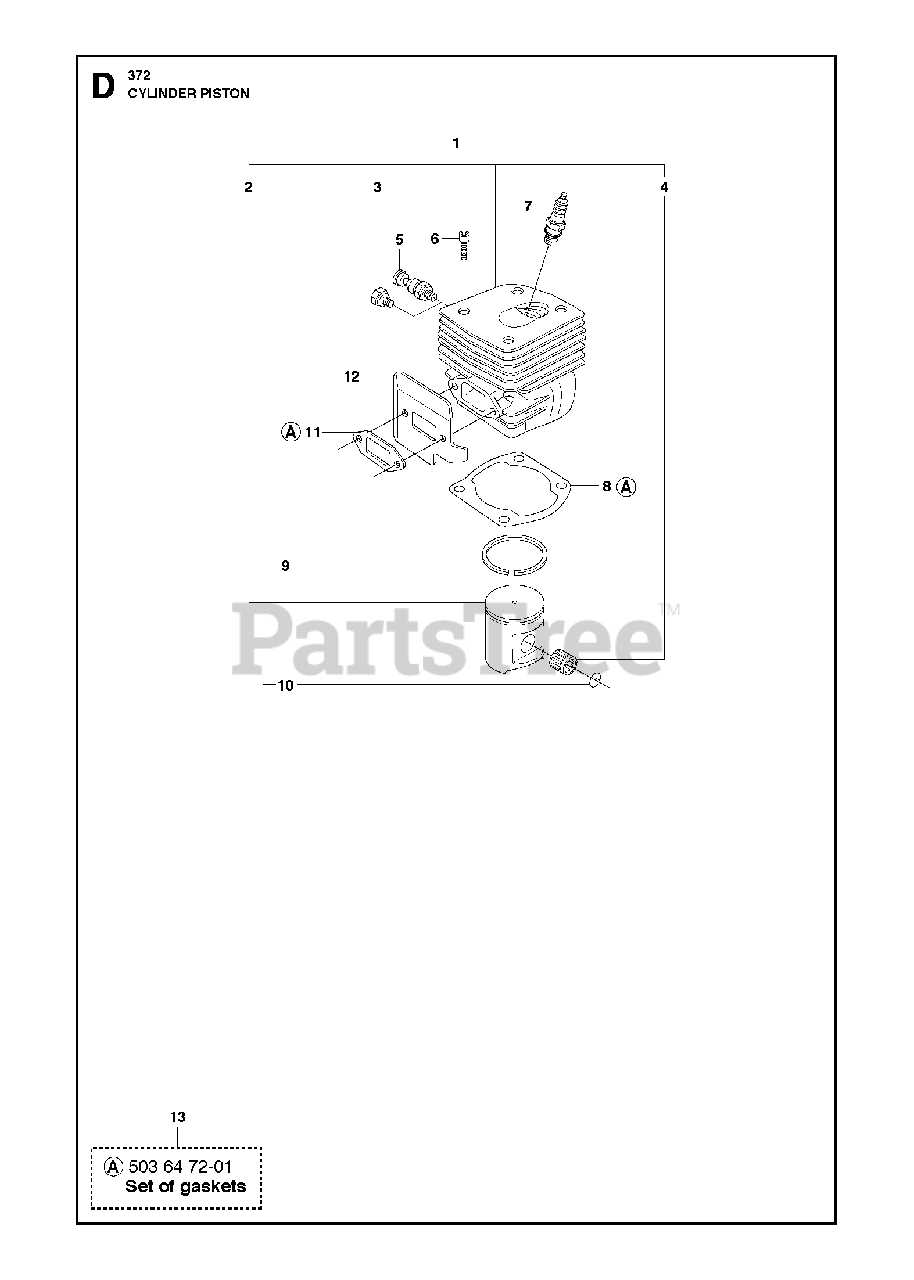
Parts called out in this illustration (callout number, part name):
1	CYLINDER ASSY
2	PISTON ASSY
2	PISTON CPL 50 MM
3	CYLINDER PLUG
4	SUPPORT BUSHING
5	DECOMPRESSION VALVE
6	SCREW MC6S 5X25
7	SPARK PLUG RCJ7Y
8	GASKET
9	PISTON RING
9	RP PISTON RING
10	WRIST PIN CLIP
11	GASKET
13	GASKET SET
